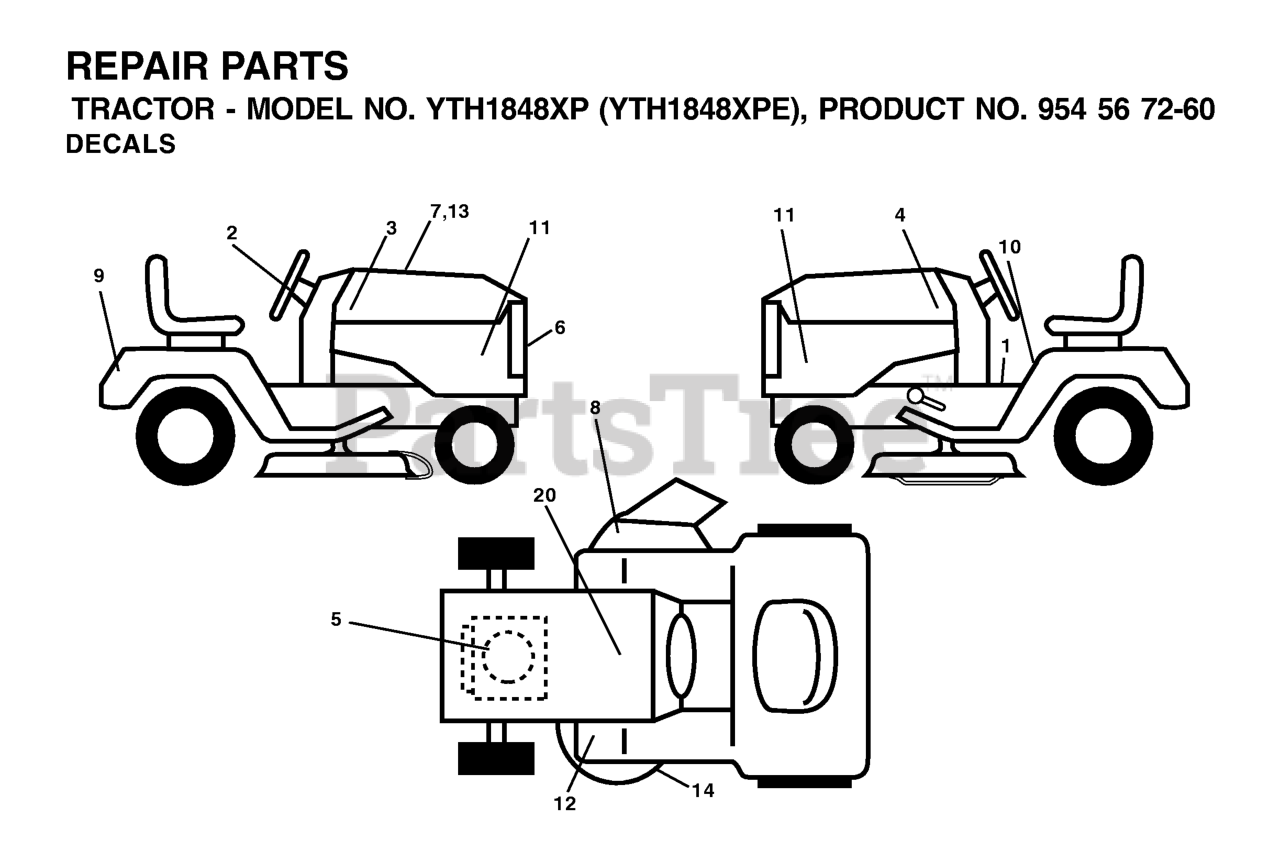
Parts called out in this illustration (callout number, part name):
2	DECAL.WHEEL.STEERING.HUSQ.PERM
6	DECAL.GRILLE.HUSQ
8	DECAL.WARN.KEEP.HAND.AWAY
9	DECAL, FENDER
10	DECAL FENDER DANGER
11	DECAL HOOD SIDES
12	DECAL CLUTCH/BRAKE
13	DECAL HOOD CUST. RESP.
14	DECAL V-BELT SCHEMATIC
20	DECAL BTRY SYMBOLS
